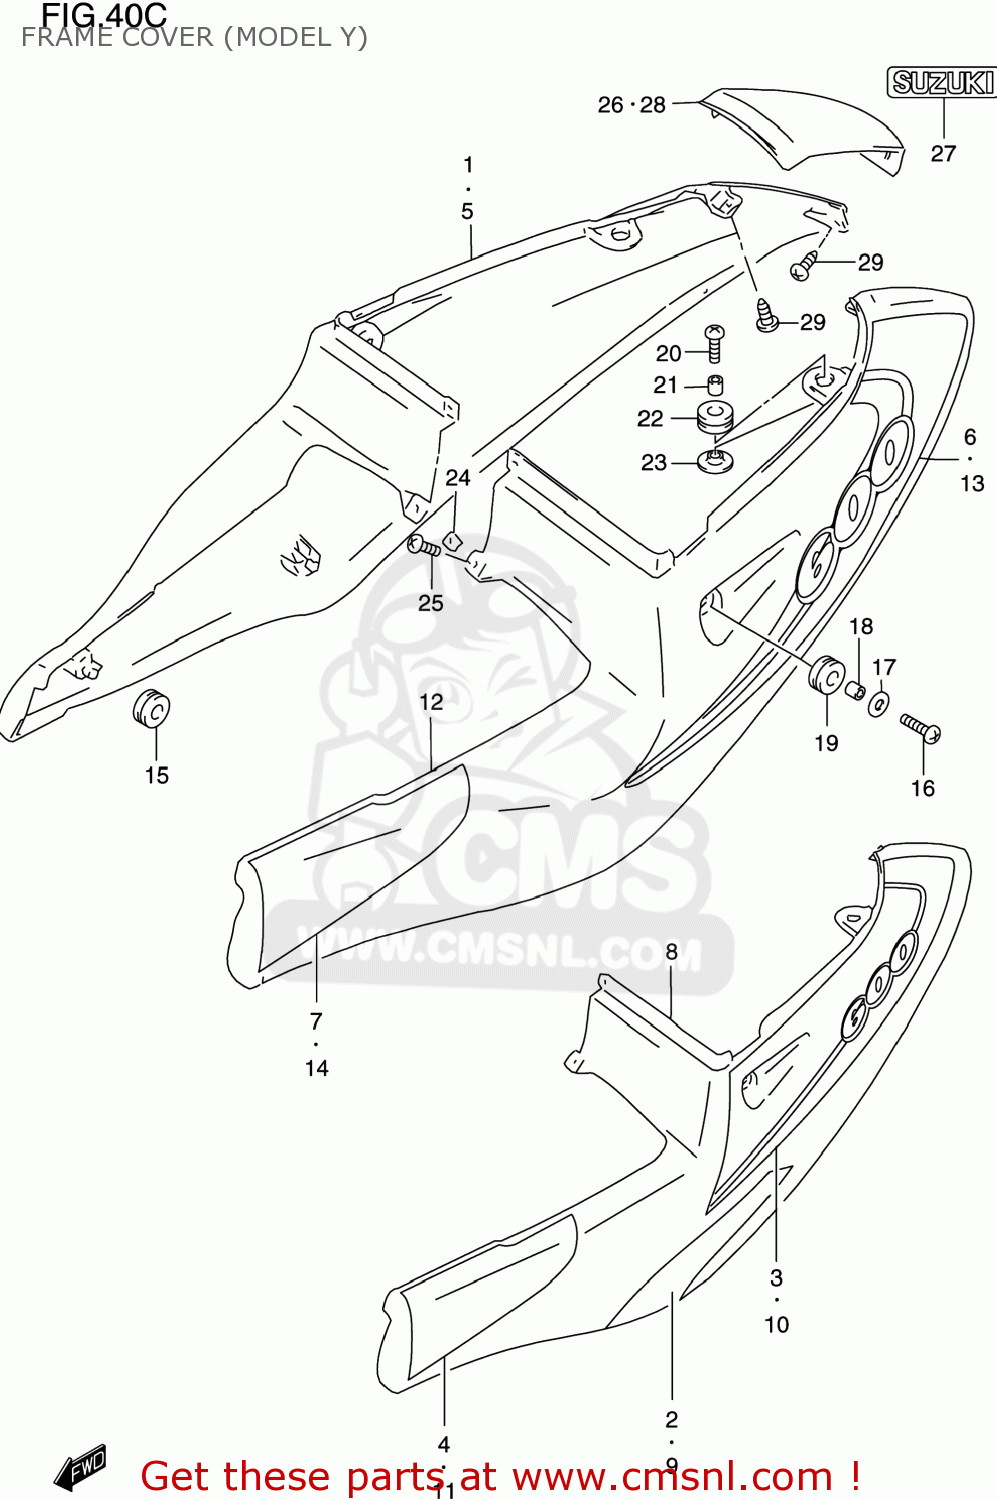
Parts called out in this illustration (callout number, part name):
1	COVER COMP,FRAME,RIGHT
2	TAPE,FRAME COVER NO.1,R
3	TAPE,FRAME COVER,R
4	TAPE,FRAME COVER,FRONT,RIGHT (
5	COVER COMP,FRAME,RIGHT
6	TAPE,FRAME COVER,R
7	TAPE,FRAME COVER,FRONT
8	COVER COMP,FRAME,LEFT
9	TAPE,FRAME COVER NO.1,L
10	TAPE,FRAME COVER,L
11	TAPE,FRAME COVER,FRONT,LEFT (
12	COVER COMP,FRAME,LEFT
13	TAPE,FRAME COVER,L
14	TAPE,FRAME COVER,FRONT
15	CUSHION
16	SCREW(6X20)
17	WASHER(6.5X22X1.6)
18	SPACER(6.5X9X6.7)
19	CUSHION
20	SCREW(6X25)
21	SPACER(6.5X10X9.4)
22	CUSHION,TAIL COVER UPR
23	CUSHION,FRAME COVER LWR
24	SCREW
25	NUT
26	COVER,FRAME CTR
27	EMBLEM,SUZUKI(WHITE)
28	COVER,FRAME CTR
29	SCREW
